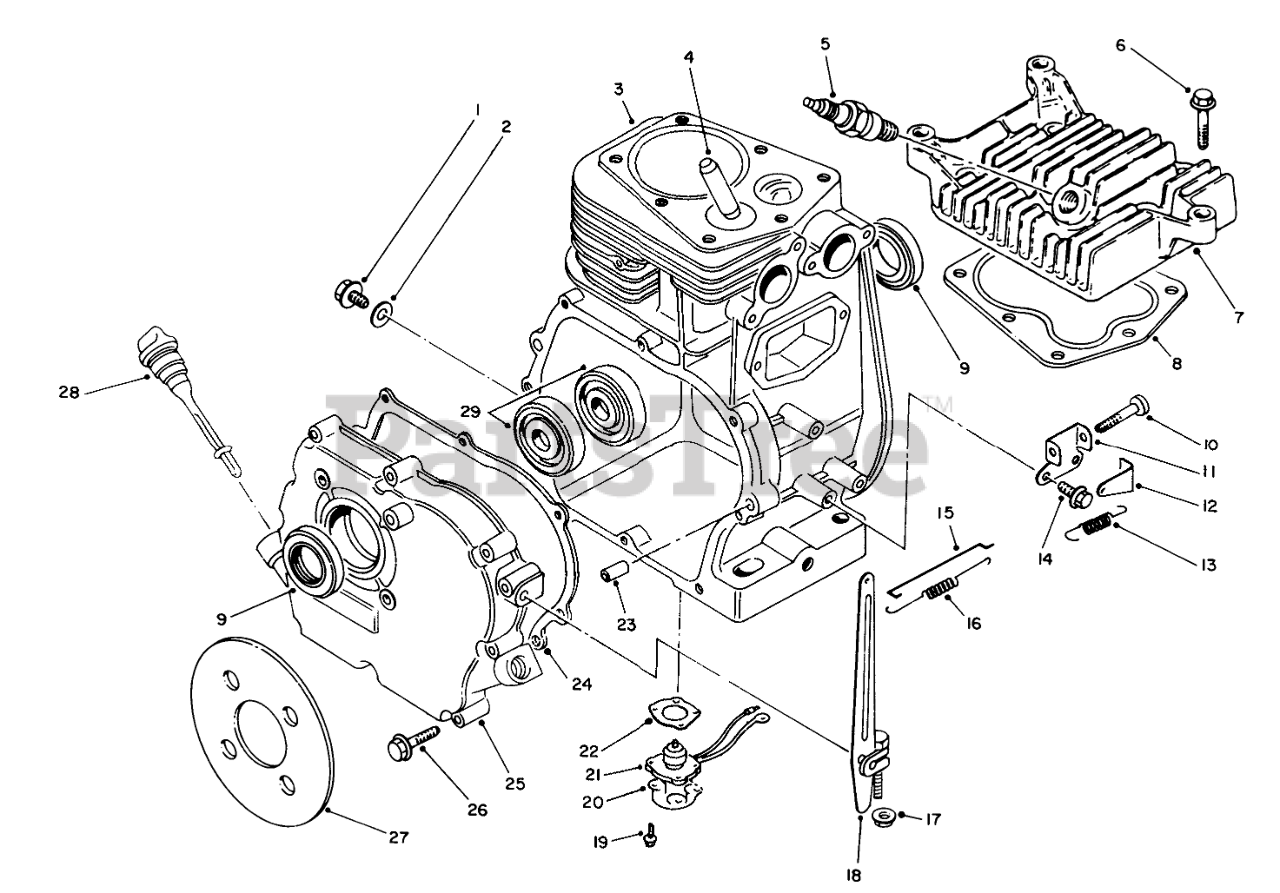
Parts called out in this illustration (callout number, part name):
1	Drain Plug
2	GASKET
3	Cylinder
4	Guide Valve
5	SPARK PLUG
7	Cylinder Head
8	GASKET
9	Oil Seal
11	Bracket
13	SPRING
15	Rod-Carburetor
16	SPRING
18	Lever-Control
20	Plate
21	SENSOR
22	GASKET
24	Gasket-Crankcase
27	Seat-Joint
28	Gauge-Oil Level
29	Bearing
